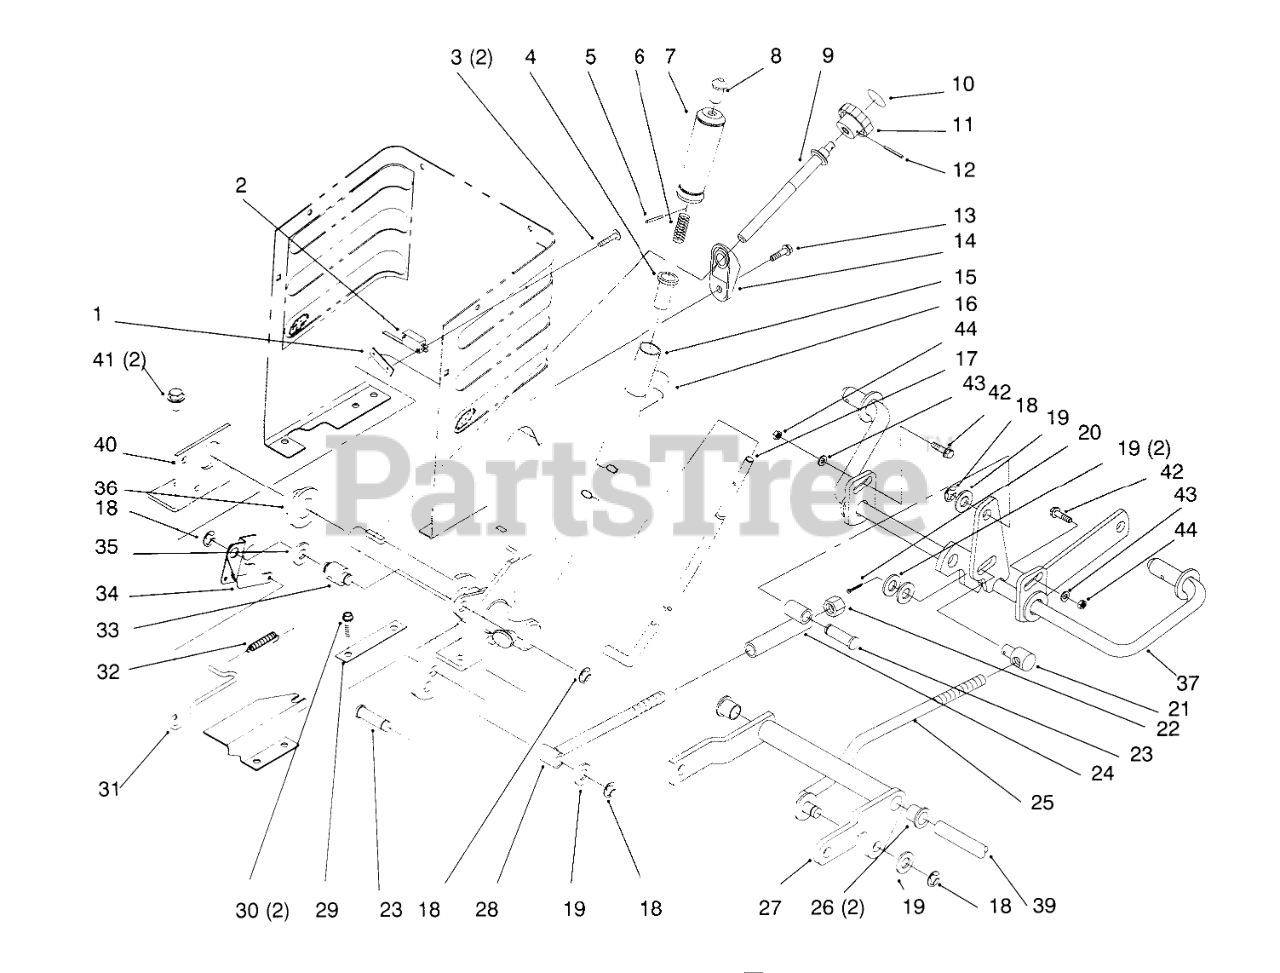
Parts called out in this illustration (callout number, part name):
1	NUT-SPEED
2	SWITCH-MICRO
3	SCREW-HH
4	RETAINER-SPRING
5	PIN-SPIROL
6	SPRING-COMPRESSION
7	GRIP-HANDLE
8	TIP-ROD
9	ROD - HOC
10	DECAL-HEIGHT KNOB
12	PIN-SPIROL
13	SCREW-HWH
14	WEDGE - HOC
15	Lever-Lift
16	Decal-Lift (Only On: 72042,72043)
16	Decal-Lift (Only On: 72062,72063,72103)
17	ROD-LEVER, LIFT
18	RING-RETAINING, EXTERNAL
19	WASHER-FLAT
20	PIN-COTTER
21	ROD-TRUNNION LIFT
22	NUT-LOCK, NI
26	BUSHING-FLANGE
27	ARM-PIVOT
30	SCREW-HWHTF
31	ROD - HOC INDICATOR
32	SPRING - EXTENSION
33	TRUNNION
34	PLATE - HOC GAGE
35	WASHER
36	BEARING-FLANGE
37	SHAFT-GAGE
39	SHAFT
40	Bracket-Pivot Linkage
41	Screw-HH (Only On: 72043,72063,72103)
41	Screw-TAP (Only On: 72042,72062)
42	BOLT-CARR
43	WASHER-FLAT
44	NUT-LOCK, NI
